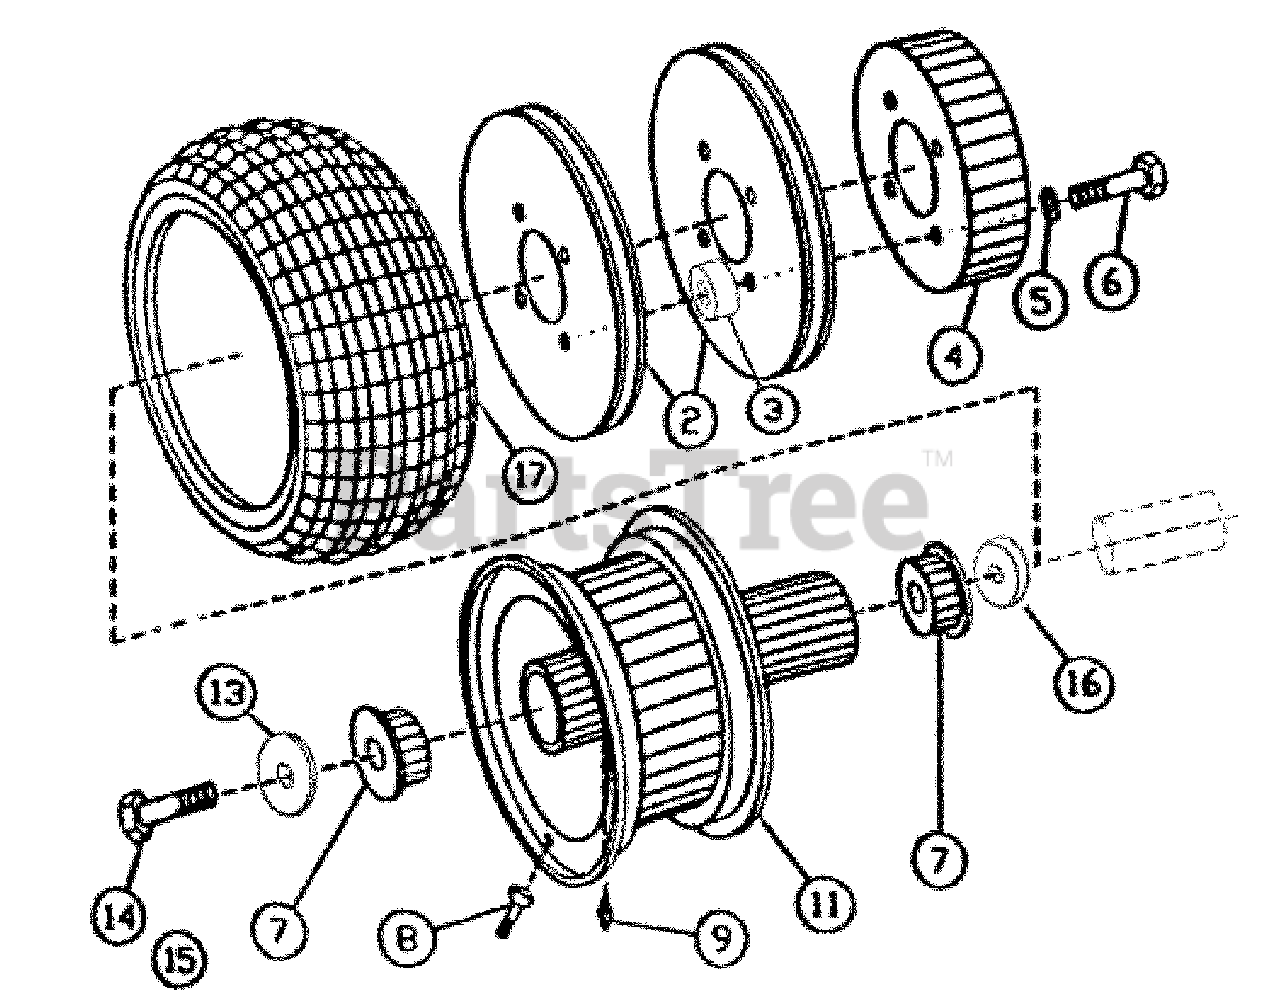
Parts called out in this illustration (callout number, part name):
2	100-110 PULLEY TRACTION
3	100-111 SPACER 11.5
4	100-112 BRAKE HUB
5	5/16HELICAL L-WASHER
6	200-060 BOLT M8`40
7	200-061 BRG 6005 2RS
8	100-113 VALVE
9	GREASE FTG (10 PACK) 200-026
11	148-013 RIM 36`&48`
13	100-019 WASHER
14	100-119 BOLT M10 LEFT
15	M10X1.5X25MM HHB GR8.8
16	100-099 SPACER 6.5
17	148-012 TIRE 13`6.5-6
